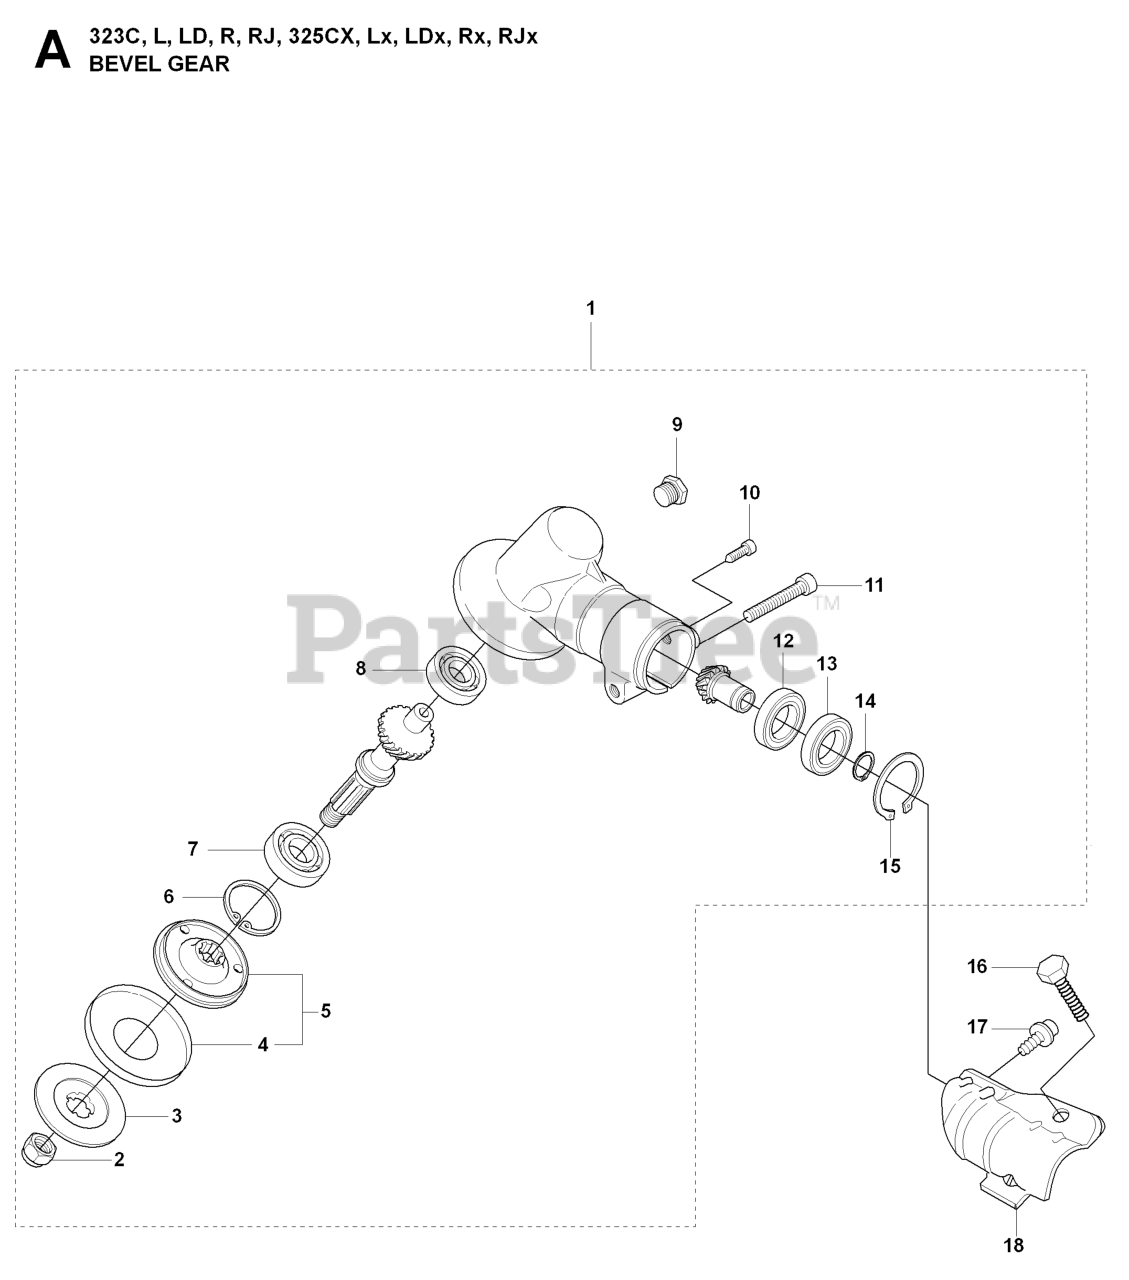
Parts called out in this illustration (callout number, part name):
1	GEAR HEAD
2	GEARHEAD NUT - BRUSHCUTTER
3	SUPPORT FLANGE
4	WASHER
5	DRIVE DISC
6	RETAINING RING SGH 28
7	BEARING
8	BALL BEARING 8X22X7/608Z
12	BALL BEARING 24X9X1/609ZR
14	RETAINING RING
15	RETAINING RING
16	SCREW M6S 6X20
18	RP BRACKET TRIMMER GUARD
